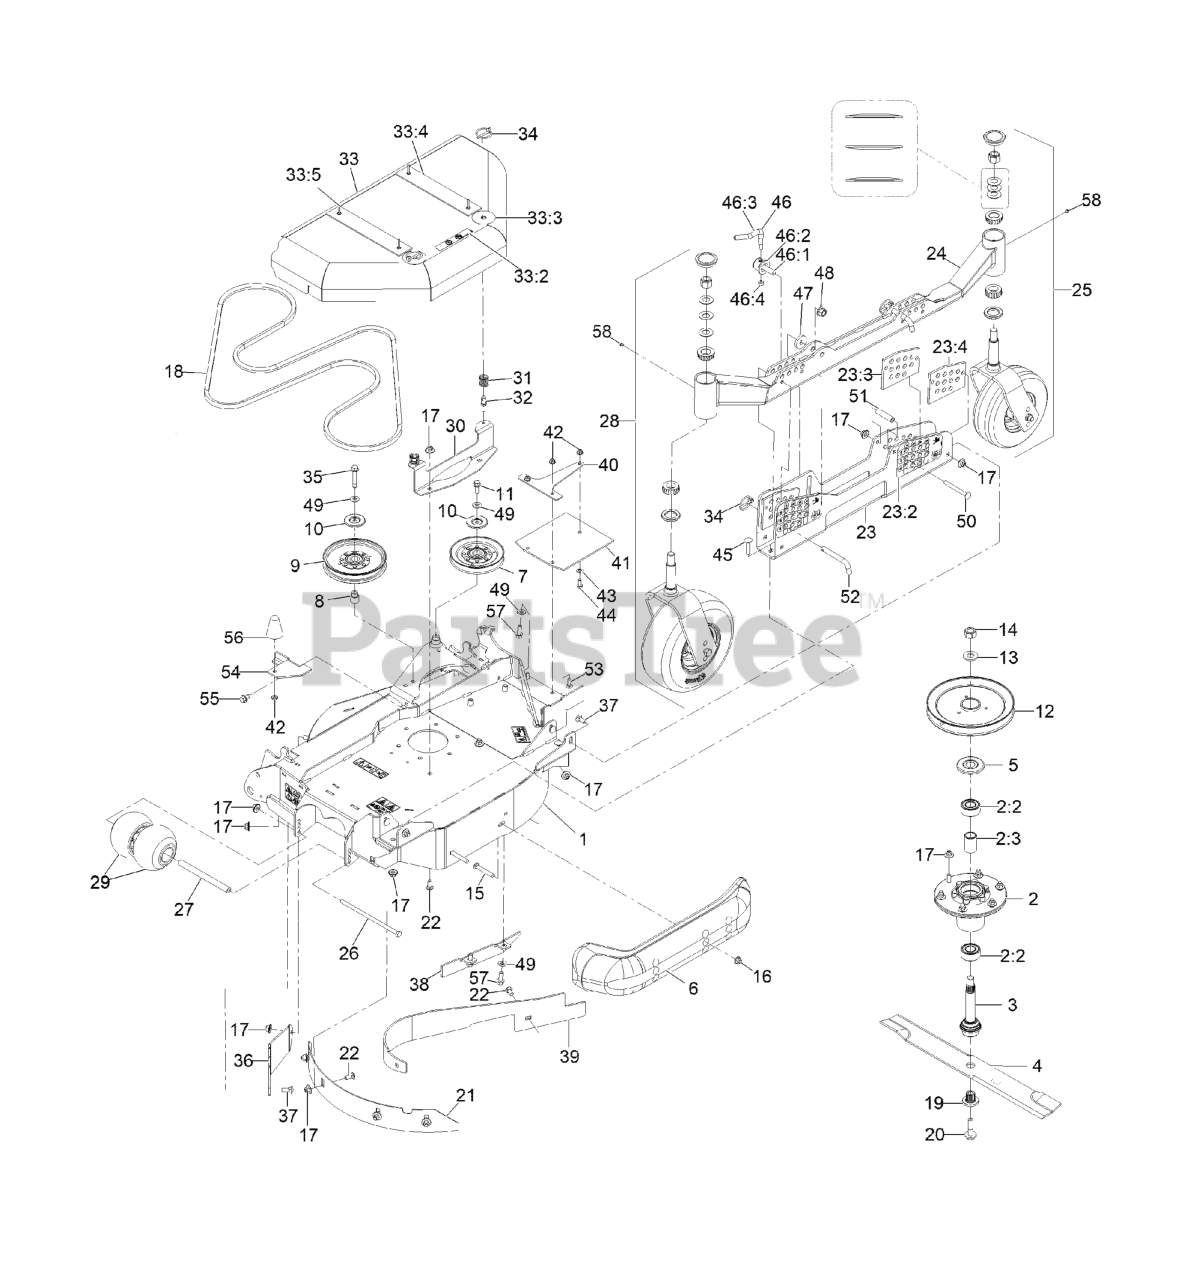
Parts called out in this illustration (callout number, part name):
1	ASM-DECK, LH WING 96
2	ASM-CUTTER HSG
2:2	BEARING-3205 TRASHGUARD
2:3	SPACER-BEARING
3	ASM-SPINDLE AND SEAL
5	GUARD-BEARING, TOP
6	SKID-BUMPER, DECK
7	IDLER-V
8	BUSHING-IDLER
9	IDLER-PULLEY
10	SHIELD-DUST
11	SCREW-HHF 3/8-16 X 1
12	SHEAVE-SINGLE 96RD
14	NUT-HEX
15	SCREW-CARR
16	NUT-HF, NI
17	Nut-Nyloc 3/8-16 Flg
19	BUSHING,SPLINED
20	SCREW,SEMS 1/2-20 X 2.19
21	BAFFLE-DEPTH, LH
22	BOLT-CARR
23	LH HOC CHANNEL ASM
23:2	DECAL-HEIGHT OF CUT-LH
23:3	PLATE-GUIDE, HOC (LH)
23:4	PLATE-GUIDE, HOC (RH)
24	TUBE-HOC, LH
25	Caster/Wheel ASM
26	SCREW-HH
27	SPACER-WHEEL
29	ROLLER-SCALP, ANTI
30	BRACKET-SHIELD MOUNT, OUT
32	PIN, SPRING
33	ASM-Wing Shield LH
33:2	DECAL-NO STEP
33:3	DECAL-SCRATCH COVER
33:4	Plate-Uhmw 2"
33:5	Rivet-Pop
34	PIN-LYNCH
35	SCREW-HHF
36	PLATE-FILL, LH DECK
37	BOLT-CARR
38	Fin-Baffle, Discharge Wing (LH)
39	BAFFLE-DOGLEG, CENTER (RH
40	SUPPORT-FLAP, LH
41	GUARD-TIRE, LH
42	NUT-HF, NI
43	WASHER-PLAIN
44	SCREW-HH
45	SCREW-CARR
46	LEVER ASM
46:1	SCREW-LOCK
46:2	CAP-LOCK
46:4	NUT-LOCK, NI
48	Nut-Lock 1/2-13
49	WASHER-BELLEVILLE
50	SCREW-CARR
52	PIN-HOC
53	BOLT-CARR
54	BRACKET-COVER RETAINER
55	SCREW-HWH
56	BUMPER-RUBBER
57	SCREW-HHF
